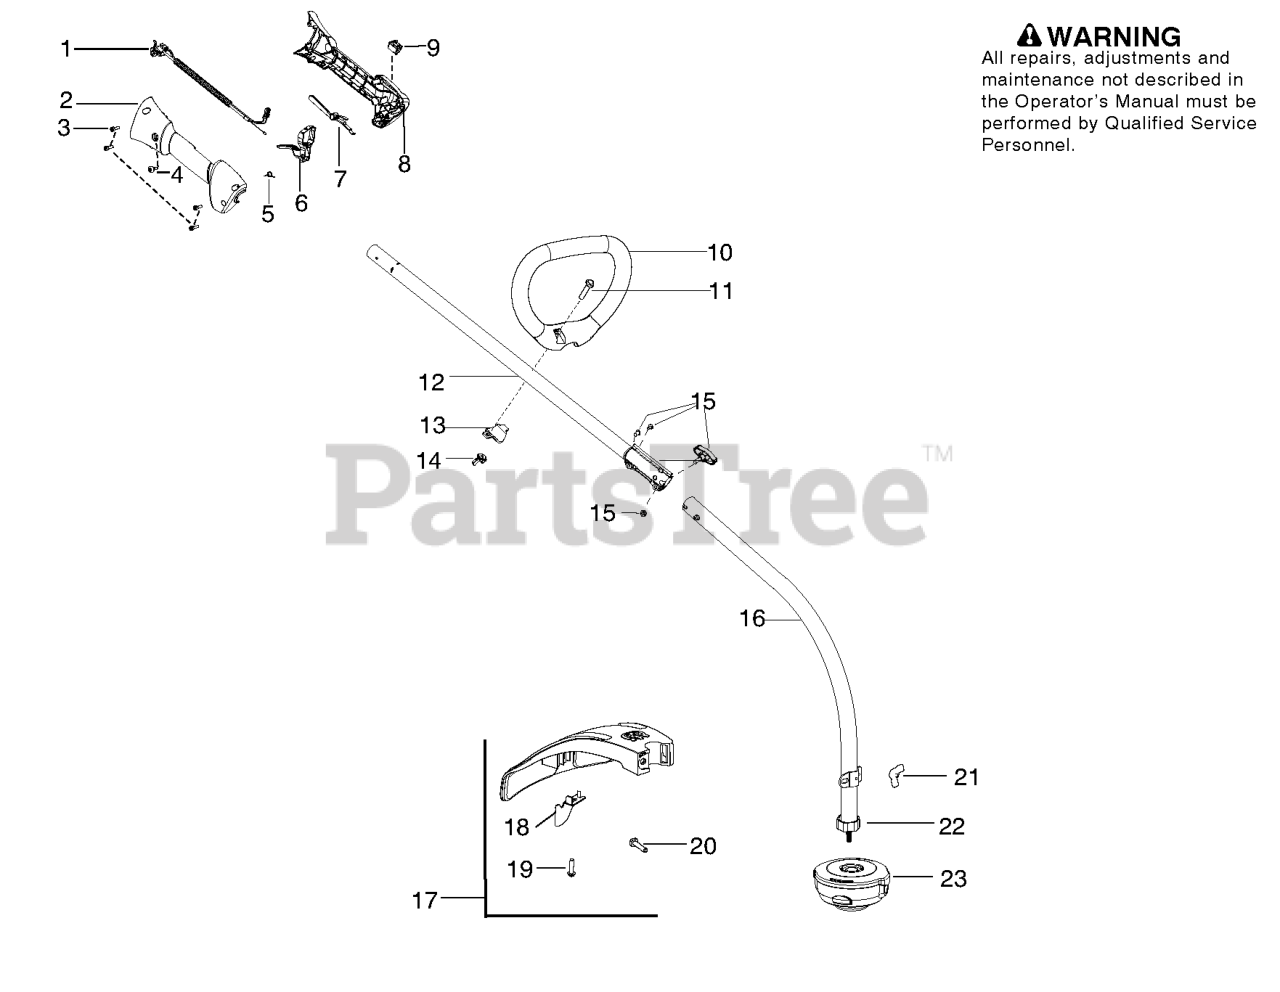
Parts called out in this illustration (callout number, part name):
1	Assy-Cable/Wire Harness
2	Housing-Throttle (RH)
3	Screw
4	Screw
5	SPRING TRIGGER
6	Trigger
7	Lockout-Throttle
8	Housing-Throttle (LH)
9	Kit-Switch
11	BOLT, TYPE 2
12	KIT UPPER SHAFT SILVER
13	CLAMP ASSIST HANDLE
14	WINGNUT, TYPE 2
15	ASSY COUPLER BLACK
16	KIT DRIVESHAFT
17	TRIMMER GUARD 128C
20	BOLT, TYPE 2
21	WINGNUT, TYPE 2
22	Dust Cup
23	Head - Cutting
